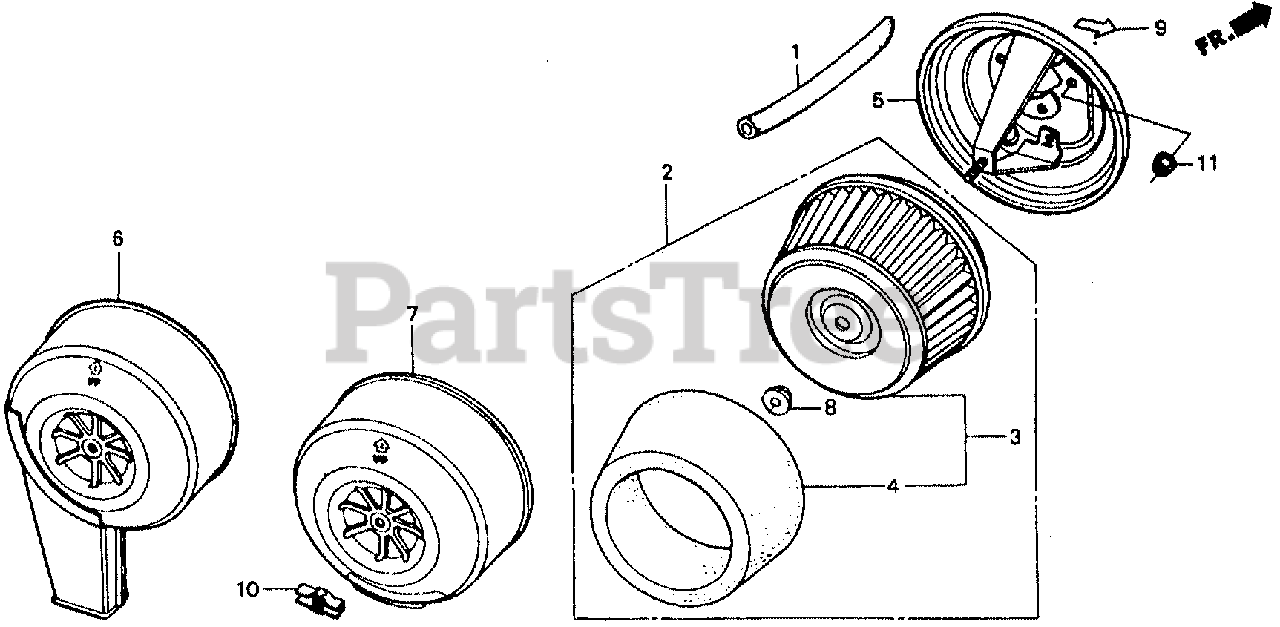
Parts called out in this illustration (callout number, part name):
1	TUBE, BREATHER
2	ELEMENT SET, AIR CLEANER
2	ELEMENT, AIR CLEANER
3	ELEMENT SET, AIR CLEANER
3	ELEMENT, AIR CLEANER
4	FILTER (OUTER)
5	HOUSING, AIR CLEANER
6	COVER, AIR CLEANER
7	COVER, AIR CLEANER
8	GROMMET, AIR CLEANER
9	MARK, CHOKE
10	WINGNUT, AIR CLEANER COVER
11	NUT, FLANGE (6MM)
